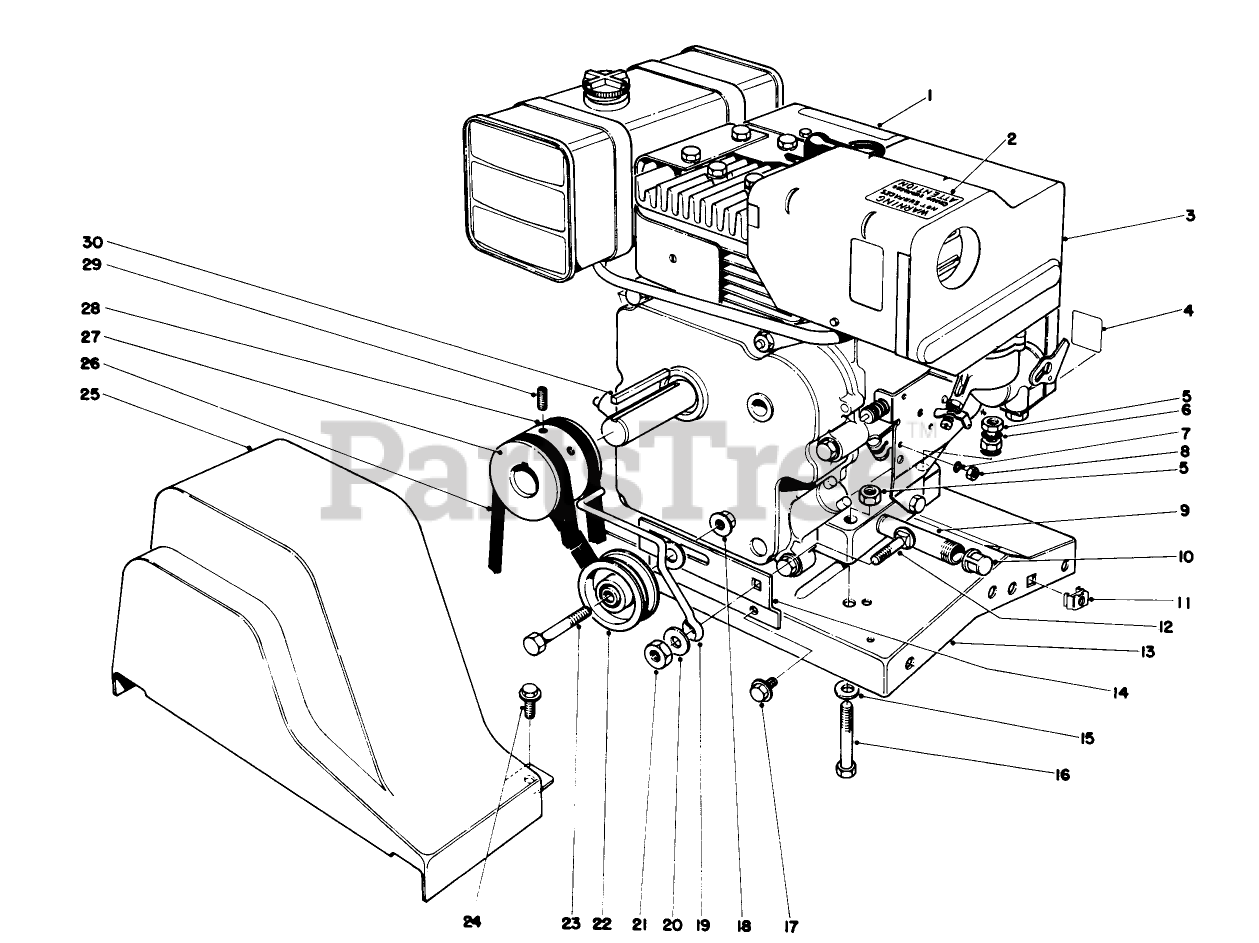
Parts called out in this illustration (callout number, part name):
1	CAUTION DECAL
2	Decal Hot Surface Warning
3	Engine
4	CHOKE DECAL
5	NUT-LOCK, NI
6	WASHER-LOCK, INTERNAL
7	WASHER-LOCK/INT
8	NUT-LOCK
9	NIPPLE-PIPE
10	CAP-PIPE
11	Retained Nut
12	SCREW-CARR
13	Base-Engine
14	Belt Idler Bracket
15	WASHER-PLAIN
16	SCREW-HH
17	SCREW-HHFTF
18	NUT-HHF, WHIZ
19	BELT GUIDE
20	WASHER-FLAT
21	NUT-HEX
22	PULLEY B
23	SCREW-HH
24	SCREW-HWH
25	BELT GUARD
26	V-BELT
27	ENGINE PULLEY
28	V-BELT
29	Screw-Set
